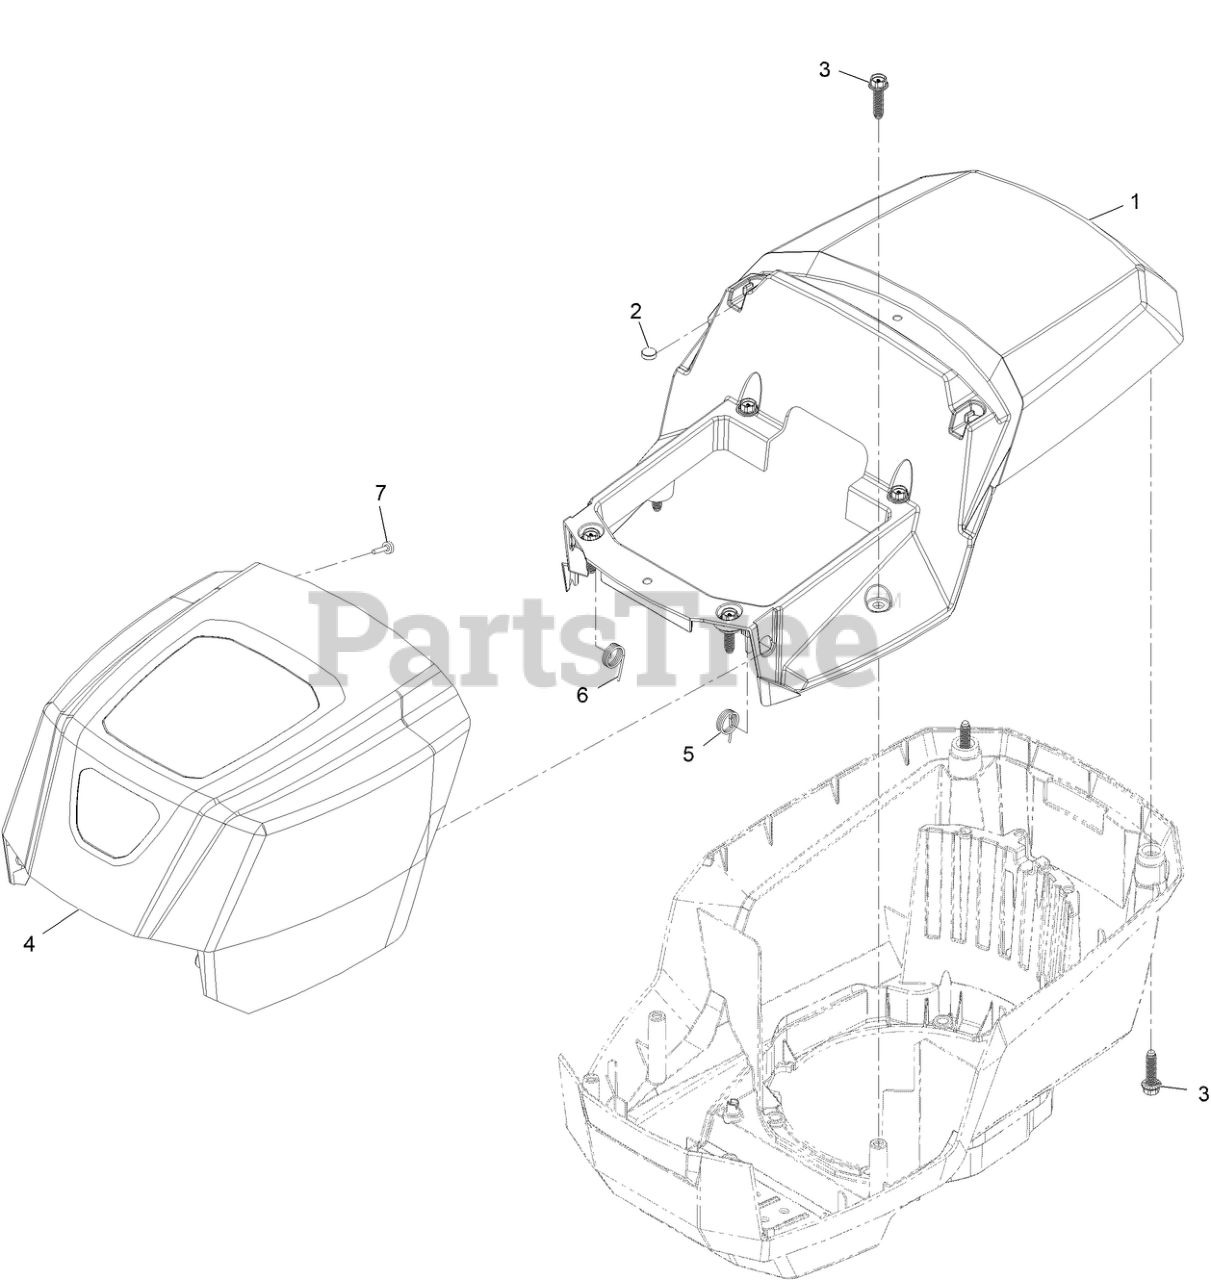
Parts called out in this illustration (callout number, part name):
1	SHROUD-UPPER
2	MAGNET
3	SCREW-FLANGE, PLASTIC
5	SPRING-LH
6	SPRING-RH
7	SCREW-PPH
